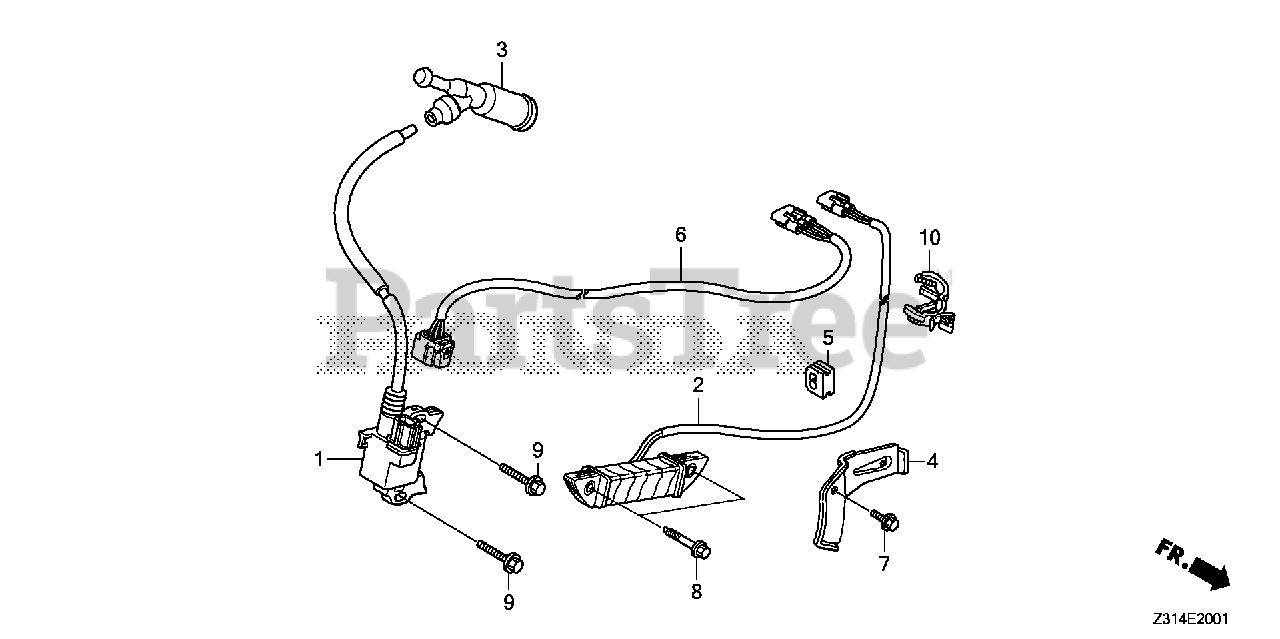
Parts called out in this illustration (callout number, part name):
1	COIL ASSY., IGNITION
2	COIL ASSY., POWER
3	CAP ASSY., NOISE SUPPRESSOR (NGK Y-EZD)
4	CLAMP, WIRE
5	GROMMET, WIRE
6	WIRE HARNESS ASSY., ENGINE
7	BOLT, FLANGE (6X12) (CT200)
8	BOLT, FLANGE (6X32) (CT200)
9	BOLT, FLANGE (6X28) (CT200)
10	CLIP, HARNESS
